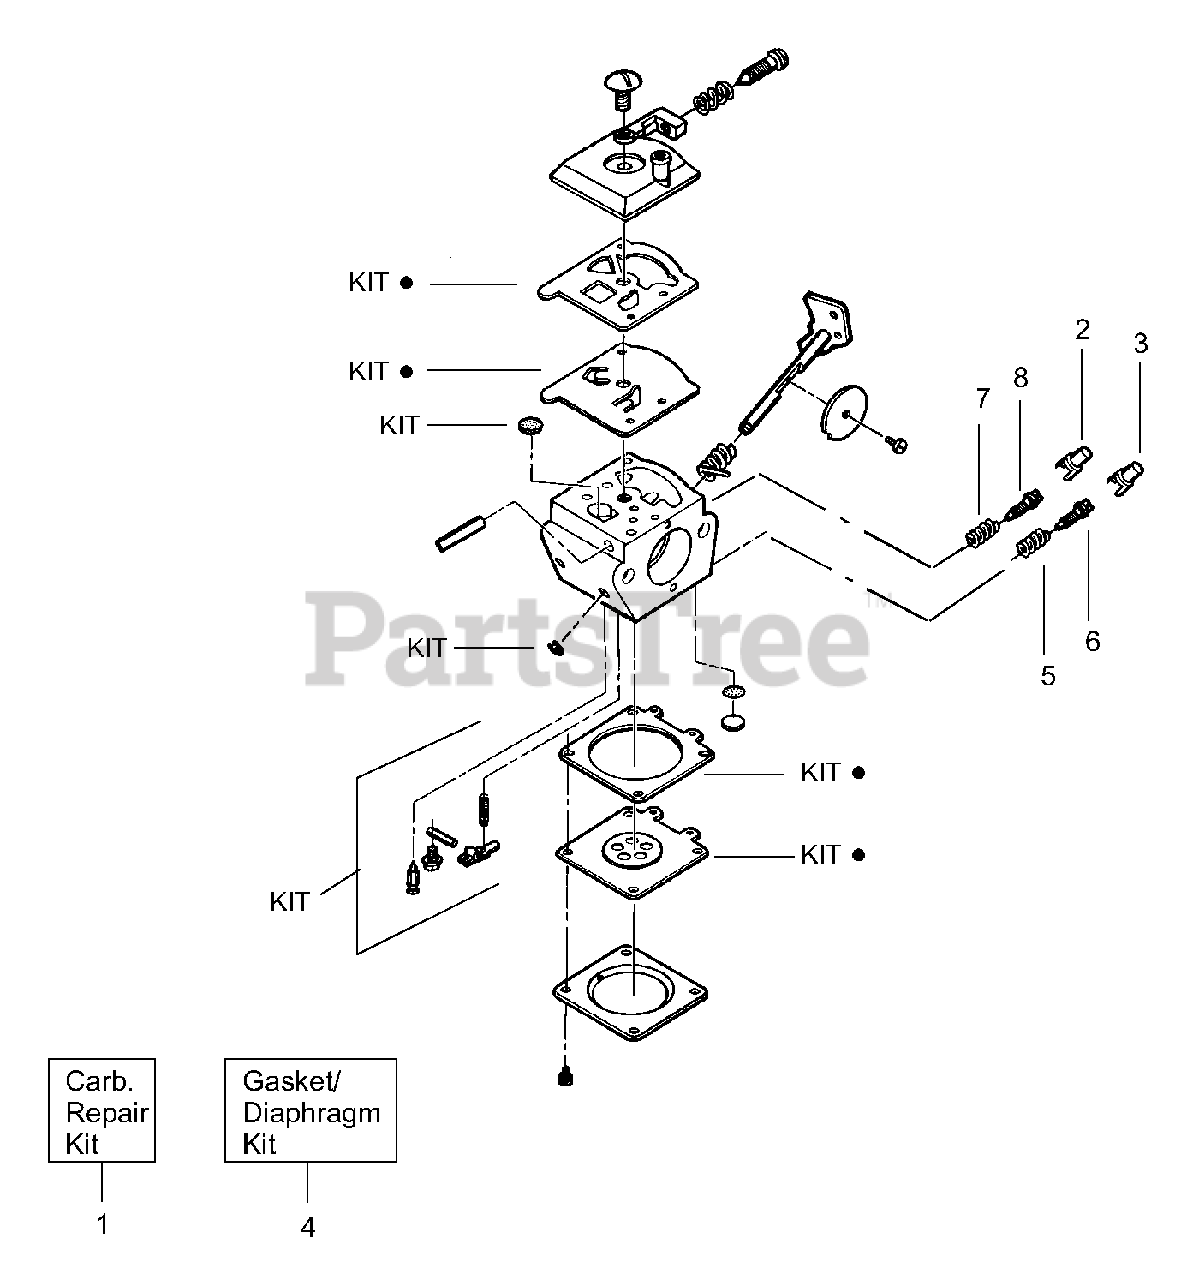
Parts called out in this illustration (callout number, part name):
1	Carburetor Repair Kit
2	Limiter Cap (High-Red)
3	Limiter Cap (Low-Blue)
4	Gasket/Diaphragm Kit
5	Needle Spring-Low Speed
6	Needle-Low Speed
7	Needle Spring-High Speed
8	Needle-High Speed
